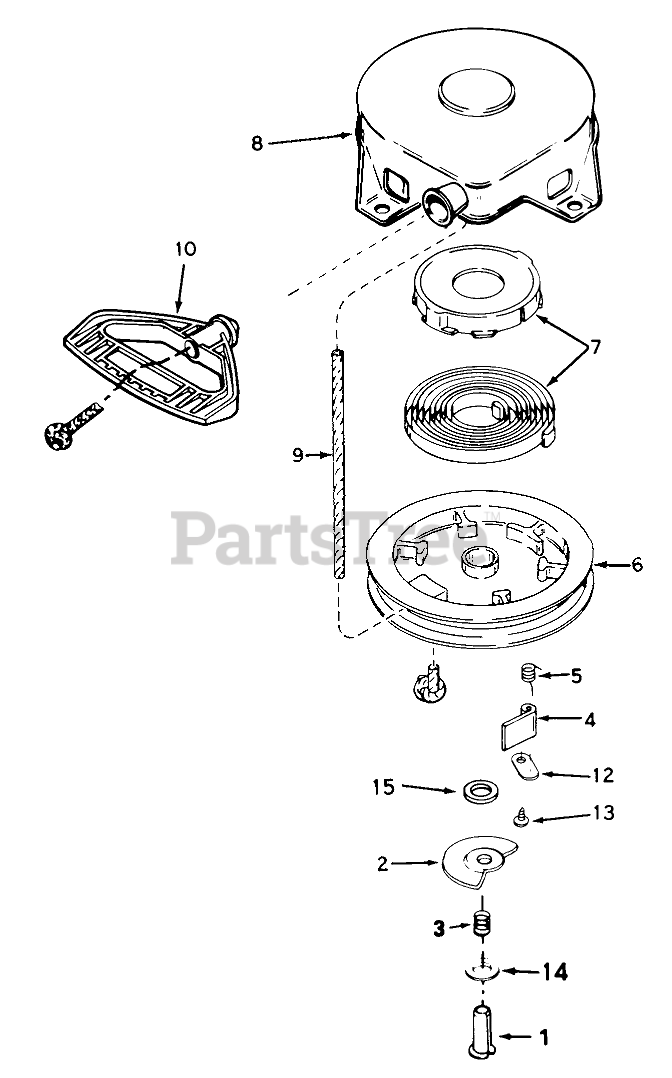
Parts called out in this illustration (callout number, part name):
1	Pin, Spring (Incl. Ref. #15)
3	Brake Spring
4	Dog-Starter
5	Spring-Dog
7	Spring & Keeper Assy
8	Housing-Starter
9	Rope-Starter
10	Handle-Starter, Mitten Grip
12	Retainer-Dog
